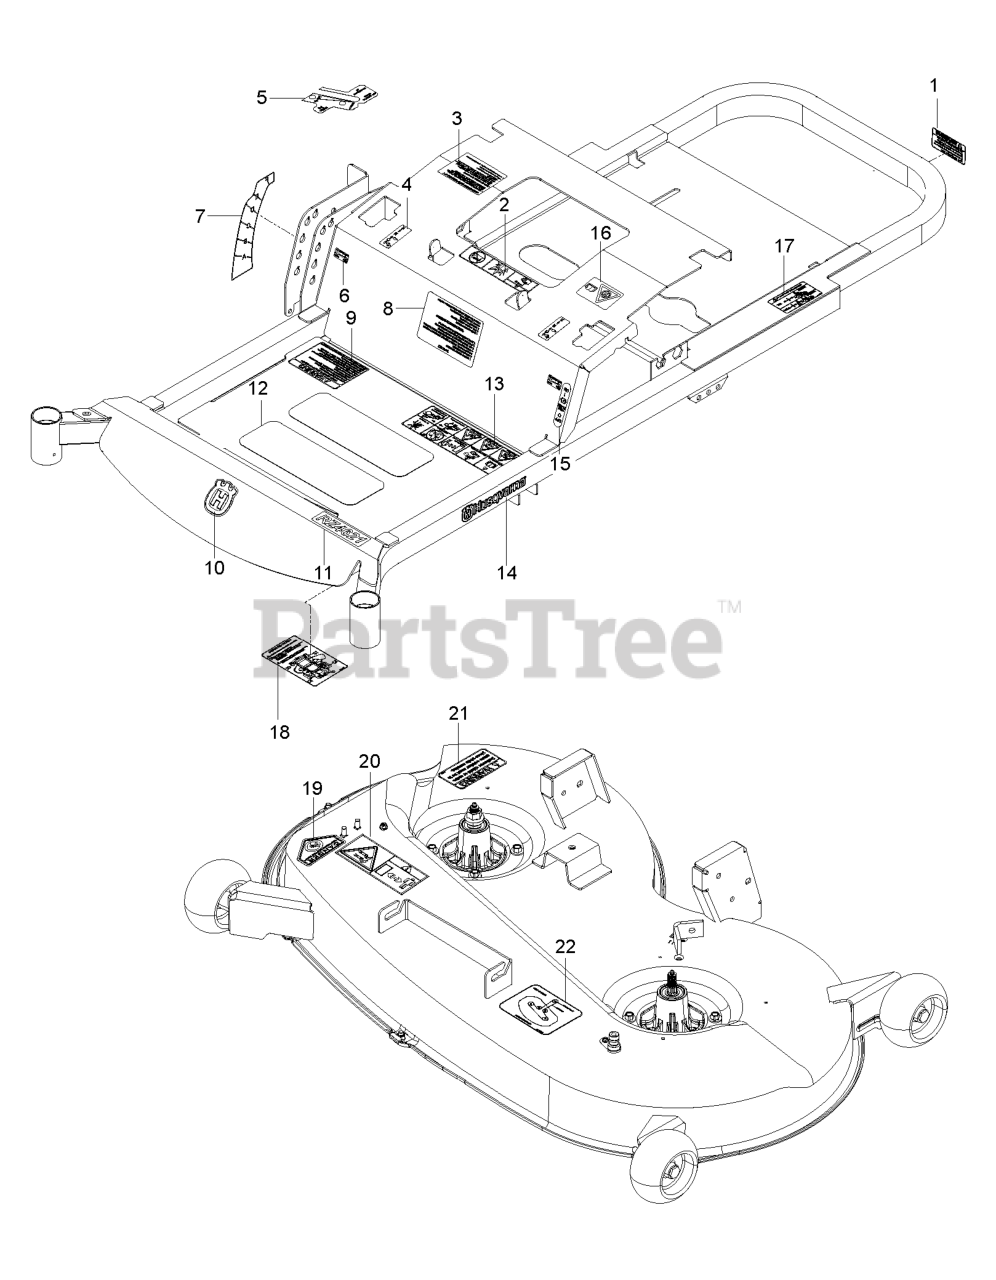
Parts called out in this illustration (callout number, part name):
1	DECAL, PROP. 65
2	EURO DECAL-BATTERY WARNIN6
3	DECAL, CUSTOMER RESPNSIBILITY
4	DECAL, MOTION CONTROL
5	DECAL, CTRL PANEL, HUSQ
6	DECAL, F.S.T.
7	DECAL, HEIGHT
8	DECAL, START
9	DECAL, WARNING
10	DECAL.AUGER.HUSQ.CROWN.SNOW
11	DECAL, RZ4623
12	ANTI-SKID PAD
13	DECAL, SAFETY WARNING
14	RP.DECAL.BADGE.170MM.TEXTLOGO
15	DECAL, PARK BRAKE
16	DECAL, EXITING MOWER
17	DECAL, DO NOT TOW
18	DECAL, SERVICE
19	DECAL, EURO SEVERING
20	DECAL, CPSC
21	DECAL, CAUTION
22	DECAL, BELT ROUTING
